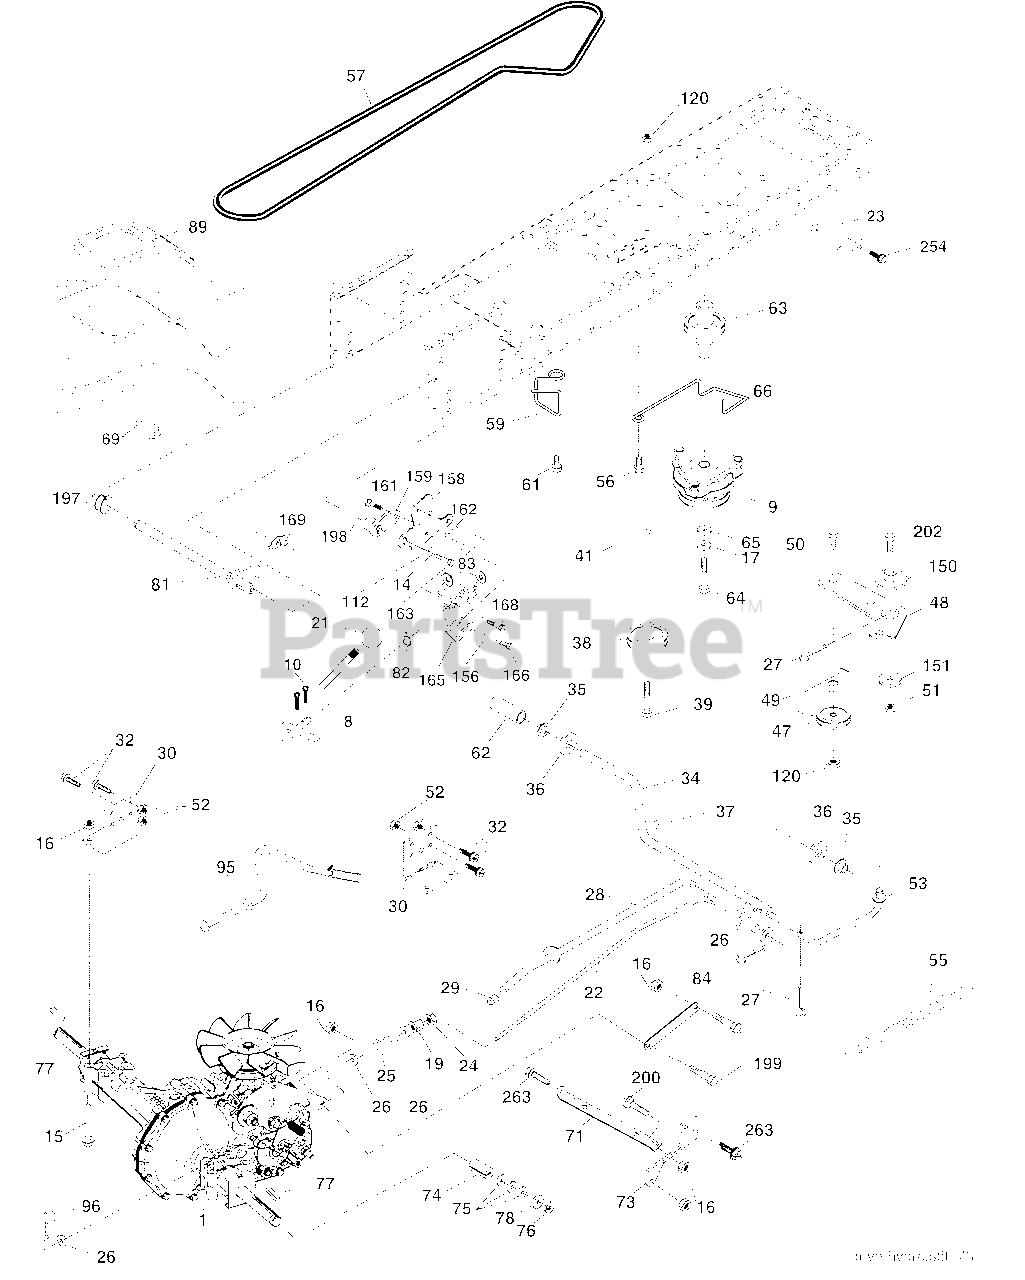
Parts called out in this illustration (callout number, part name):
8	Rod Shift Fender
9	Clutch Electric
10	Pin Cotter 1/8 x 1 CAD
14	Washer Lock Hvy Helical
15	Bolt Hex Flghd 5/16-18 Gr. 5
16	Nut Lock Hex W/Ins. 5/16-18 unc
17	Washer 1-1/2 OD x 15/32 ID x .250
19	Nut Lock Hex W/Wsh 3/8-16 unc
22	Rod, Brake Hydro
23	Bracket Anti-Rot
24	Locknut
25	Spring, Brake Rod
26	Washer
27	Pin Cotter 1/8 x 3/4 CAD.
28	Rod, Parking Brake
29	Cap, Parking Brake
30	Bracket, Transaxle
32	Bolt Hex Hd 5/16-18 unc x 3/4
34	Shaft, Foot Pedal Nibbed
35	Bearing, Nylon
37	Pin, Roll
38	Pulley, Idler, Flat Composite
39	Bolt 3/8-16 x 2-3/4 Gr. 5
41	Keeper, Belt Idler Fool-Proof
47	Pulley, Idler, V-Groove
48	Bellcrank Clutch Grnd Drv Stl
49	Retainer, Belt
50	Bolt Carr. SH 3/8-16 x 1-1/2 Gr. 5
52	Nut Crown Lock 5/16-18
53	Link, Clutch
55	Spring, Return, Clutch
56	Screw 3/8-16 x 1-1/4
57	V-Belt, Ground Drive
59	Keeper, Center Span
61	Screw 3/8-16 x .875
62	Cover, Pedal
63	Pulley, Engine
64	Bolt Hex 7/16-20 x 4 x Gr. 5
65	Washer
66	Keeper Belt Engine Hydro
69	Screw Hex Wsh Hi-Lo 1/4-1/2 unc
71	Strap Torque Lh Hydro
73	Strap Torque Rh Hydro
74	Spacer, Axle
75	Washer 25/32 x 1-1/4 x 16 Ga.
77	Key, Square
78	Washer 25/32 x 1-5/8 x 16 Ga.
81	Shaft Asm. Cross Hydro
82	Spring Torsion T/A
83	Washer 17/32 x 3/4 x 16 Ga.
84	Link Transaxle
89	Console, Shift
95	Control Asm. Bypass Hydro
96	Retainer Spring 1" Zinc/Cad
112	Washer 9/32 x 3/4 x 10 Ga.
120	Nut Lock 3/8-16
150	Spacer Retainer
151	Washer 13/32 x 2 x 10 Ga.
156	Washer Srrted 5/16 ID x 1.125
158	Bracket Shift Mount
159	Hub Shift
161	Bolt Rdhd Sqnk 1/4-20 x 3/4 Gr. 5
162	Nut Crownlock 1/4-20 unc
163	Bolt Hex Fin 1/4-20 unc x 1 Gr. 5
165	Bracket Pivot Lever
166	Screw 5/16-18 x 5/8
168	Bolt Shoulder 5/16-18 x .561
169	Plate Fastening Lt\
197	Nyliner Snap-In 5/8" ID
198	Washer Nyliner 7/8 ID x .105
199	Bolt Shoulder 5/16-18 unc
200	Bolt Rdhd Sq Neck 5/16-18 unc x 1
202	Bolt 3/8-16 x 1-3/4 Gr. 5
254	Screw 3/8-16 x 1
263	Screw Hexwsh Thdr 3/8-16 x 3/4
